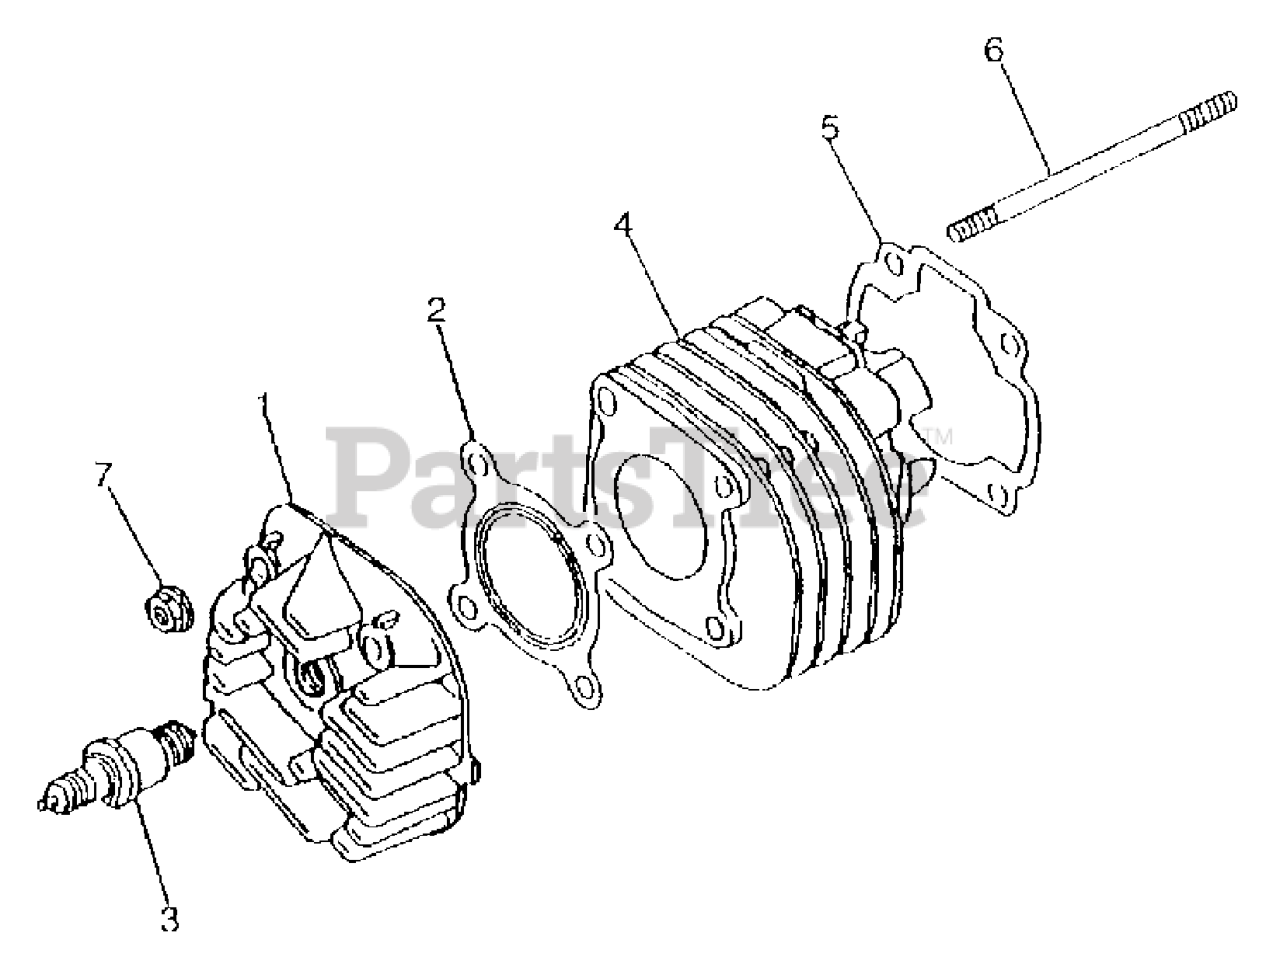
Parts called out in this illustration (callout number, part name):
1	HEAD, CYLINDER
2	GASKET, CYLINDER HEAD
3	SPARK PLUG
4	CYLINDER
5	GASKET, CYLINDER
6	STUD BOLT
